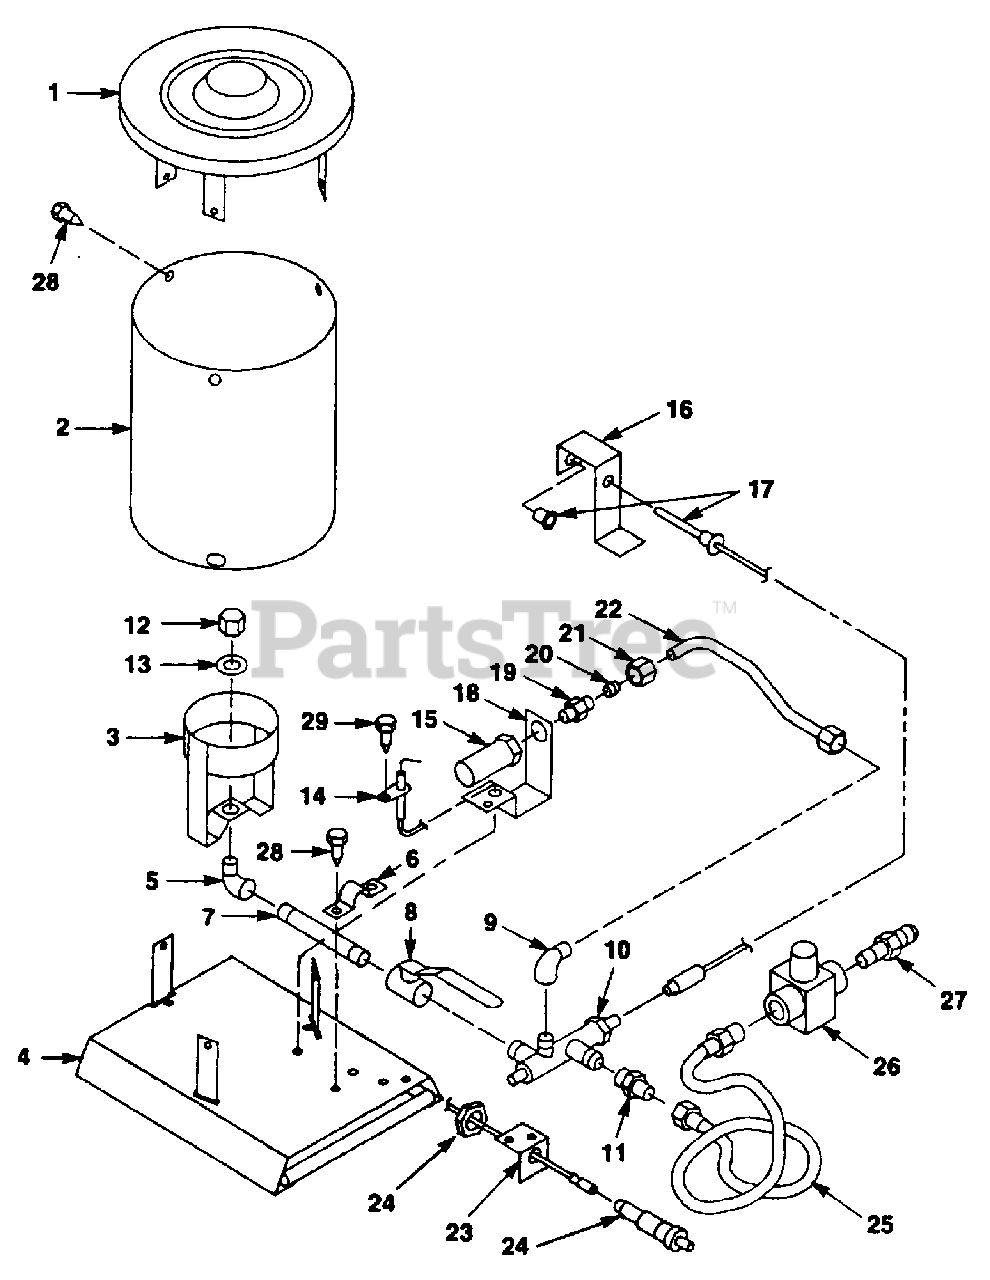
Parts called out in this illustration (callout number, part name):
1	TOP DEFLECTOR ASSY.
2	BODY- Shell
3	BURNER RING ASSY.
4	BASE ASSY.
5	FITTING- 90
6	CLAMP- Main Burner Pipe
7	PIPE- Main Burner 1/4" FPT x 1/4" FPT
8	VALVE- Main Burner Shut-Off
9	FITTING- Female Elbow 1/8" FPT x 1/4" Flare
10	VALVE- Safety
11	CONNECTOR- Female 1/4" FPT x 1/4" Flare
12	NOZZLE- Burner
13	WASHER- Shim
14	IGNITOR- Electrode
15	PILOT BURNER ASSY.
16	BRACKET- Thermocouple
17	THERMOCOUPLE 12" W/Retaining Clip
18	BRACKET- Pilot Burner
19	ORIFICE- Pilot Burner
21	NUT- Hex 7/16-24
22	PILOT FUEL TUBE ASSY.
23	BRACKET- Piezo
24	PIEZO- Ignitor W/Nut
25	HOSE ASSY.
26	VALVE- LP Gas Regulator 10 PSI
27	ADAPTOR- Excess Flow P.O.L.
